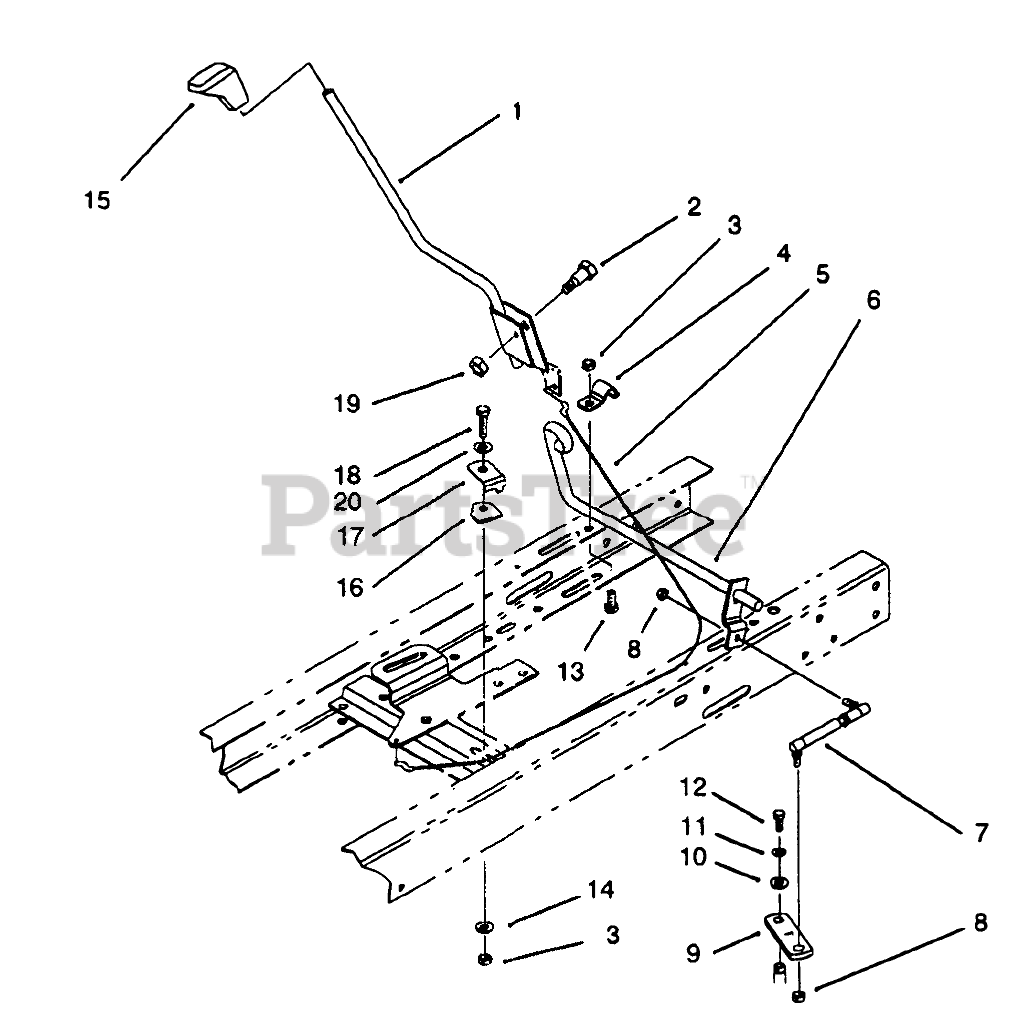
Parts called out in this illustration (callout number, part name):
1	Lever-Shift
2	SHOULDER BOLT
3	NUT-LOCK, NI
4	CLAMP-PIVOT, SHIFT
5	CABLE-CLUTCH
6	Pivot-Shift
7	TIE ROD, SHIFT
8	NUT-LOCK
9	LEVER-SHIFT
10	SPACER
11	WASHER-LOCK
12	SCREW-HH
13	SCREW-HH
14	WASHER-PLAIN
15	SHIFT KNOB
16	GUIDE-CABLE
17	KEEPER-CABLE
18	SCREW-CARR
19	NUT-LOCK, NI
20	WASHER-FLAT
